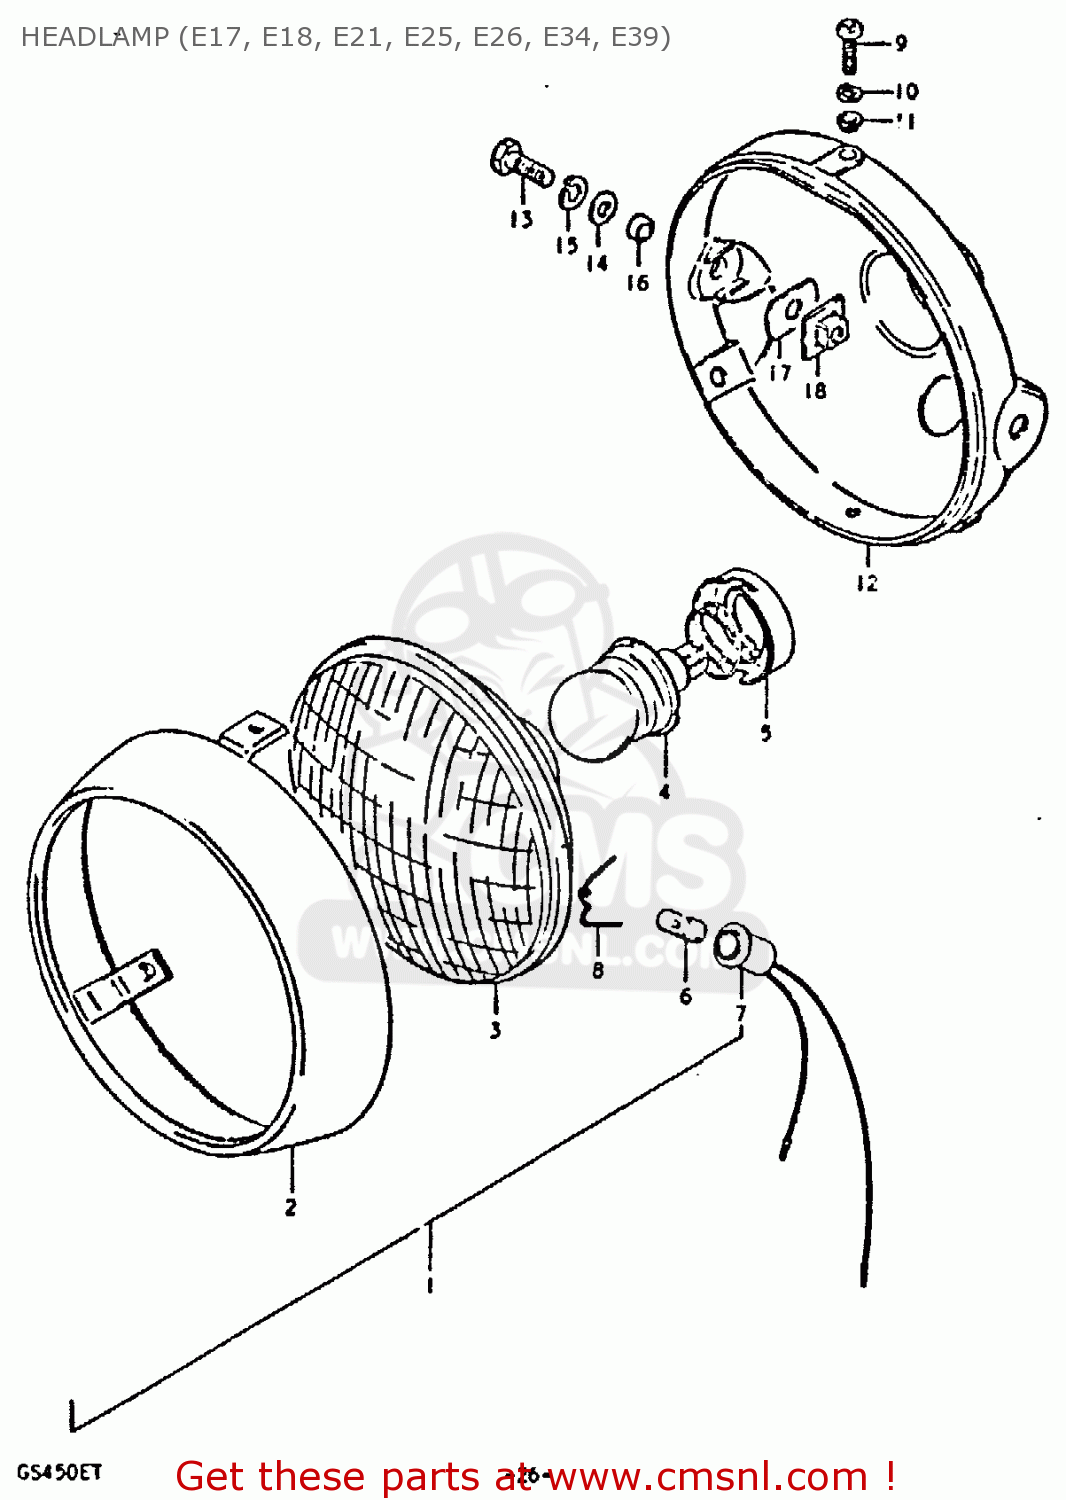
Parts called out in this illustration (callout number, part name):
1	HEADLAMP ASSY
2	RIM
3	UNIT
4	BULB(12V45/40W)
5	SETTER,BULB
6	BULB(12V4W)
7	SOCKET
8	SPRING,HEAD LA
9	SCREW
10	WASHER,LOCK
11	WASHER
12	HOUSING,HEADLAMP(BLACK)
13	BOLT
14	WASHER
15	LOCK WASHER
16	SPACER (8.8X12X7)
17	CUSHION
18	PLATE,HEADLAMP HOUSING
